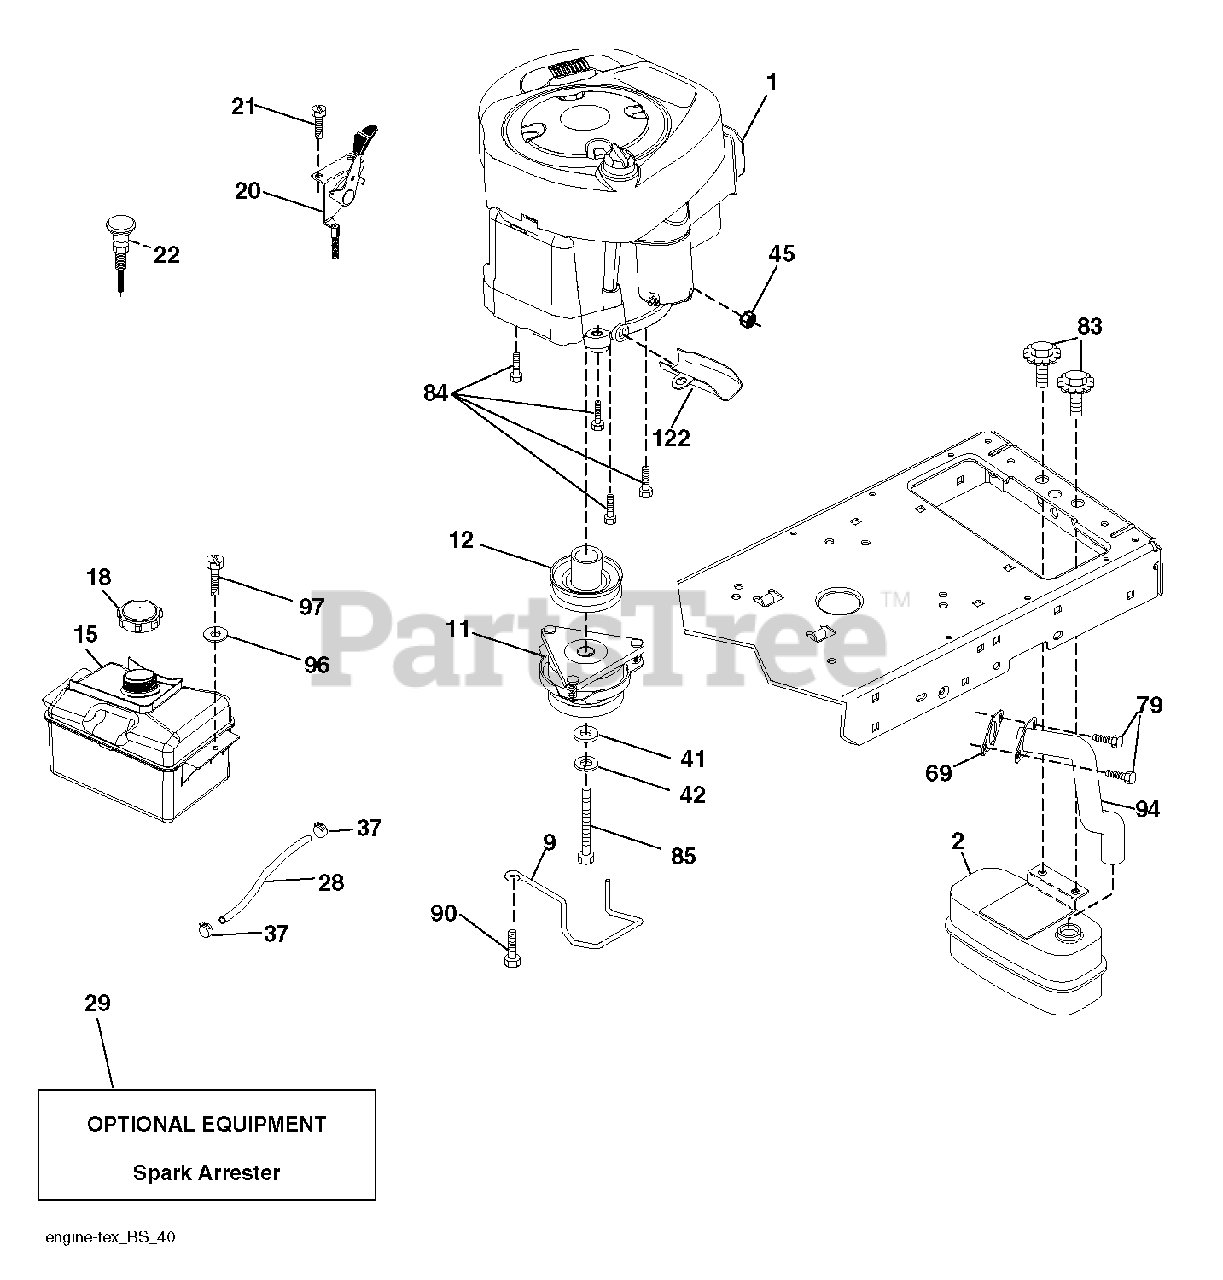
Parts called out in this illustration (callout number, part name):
2	MUFFLER.SINGLE.CYL.KOHL/B&S
9	KEEPER.BELT.ENGINE.4.2
11	CLUTCH
12	PULLEY.ENGINE.TUFFTORQ
18	CAP.FUEL.2.25"VENTED"
20	CONTROL.TH/CK.COBRA.KO
21	SCREW.#10 X 0.750.BOS THREAD
28	LINE.FUEL.20
29	ARRESTER SPARK (OPTIONAL)
37	HOSE CLAMP
42	LOCKWASHER
45	NUT
69	REPL BY 532 27 22-93
79	SCREW.SOCKET HD.5/16-1
83	BOLT, 5/16-18 X 1 3/4
84	SCREW.3/8-16
85	BOLT HEX 7/16-20X4-1/4"
90	SCREW 3/8-16X1
94	EXHAUST.TUBE.B&S.
97	SCREW HEXWSHR 1/4-20X3/4
122	EXTENSION DRAIN OIL
